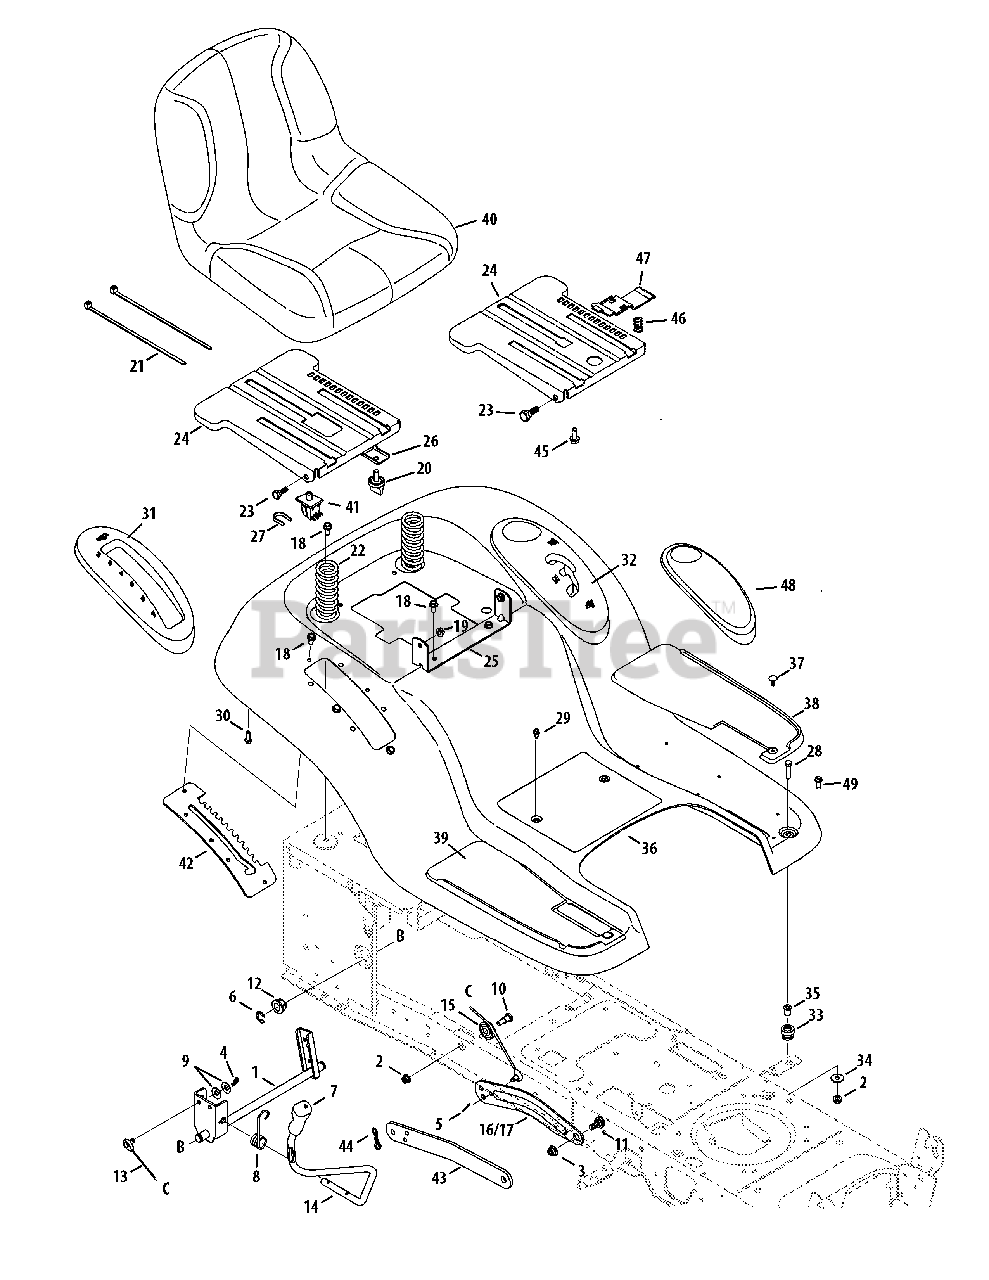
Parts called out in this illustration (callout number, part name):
1	Lift Shaft Ass’y
2	Flange Locknut 5/16-18 Gr. F, Nylon
3	Flange Lock-Nut 3/8-16 Gr. F Nylon
4	Int. Cotter Pin .072 x 1.13" Lg.
5	Bow-Tie Cotter Pin
6	E-ring .625 Shaft
7	Handle Grip
8	Tor sion Spring
9	Cupped Washer .375 ID x .870 OD x .063
10	Shoulder Screw. .437 Dia x .47
11	Shoulder Screw .500 x .25 (46"/50")
11	Shoulder Bolt 3/8-16 x .625 (38"/42")
12	Hex Flange Bear ing .630 ID
13	Lift Cable, 16.16
14	Lift Handle
15	Roller Pulley
16	Lift Arm RH
17	Lift Arm LH
18	Hex Wash Hd. Tapp Screw. 5/16-18 x .75
19	Hex Flange L-Nut 5/16-18
21	Cable Tie
22	Compression Spring 1.50 x 3.9 x .20
23	Shoulder Screw
24	Seat Mounting Bracket
25	Seat Pivot Bracket
26	Seat Bracket, Knob adjustment
27	Switch Retaining Clip
28	Hex Bolt 5/16-18 x 1.25
29	Hex Wash S-Tapp Screw 1/4-20 x .50
30	Hex Tapp Screw 1/4 x .75" Lg.
31	Lift Lever Cover
32	Shift Lever Cover
33	Grommet .4375 ID x .75
34	Flat Washer .344 ID x 1.0
35	Flange Spacer .3125 x .4375 x .625
37	Foot Pad Clips
38	Foot Pad LH
39	Foot Pad RH
40	Seat, High Back, Black
41	Seat Switch
42	Lift Bracket 6 positions (w/Electric pto)
43	Lift Link (46"/50")
44	Bow-Tie Cotter Pin (46")
45	Hex. Hd. Flg. Screw. 3/8-16 x .875
46	Compression Spring .68 x 1.065 x .055
47	Seat adjustment Lever
48	Cover (Hydrostatic Models only)
49	Hex Wash. Hd. Screw. 5/16-18 x .75 Gr. F Nyl.
